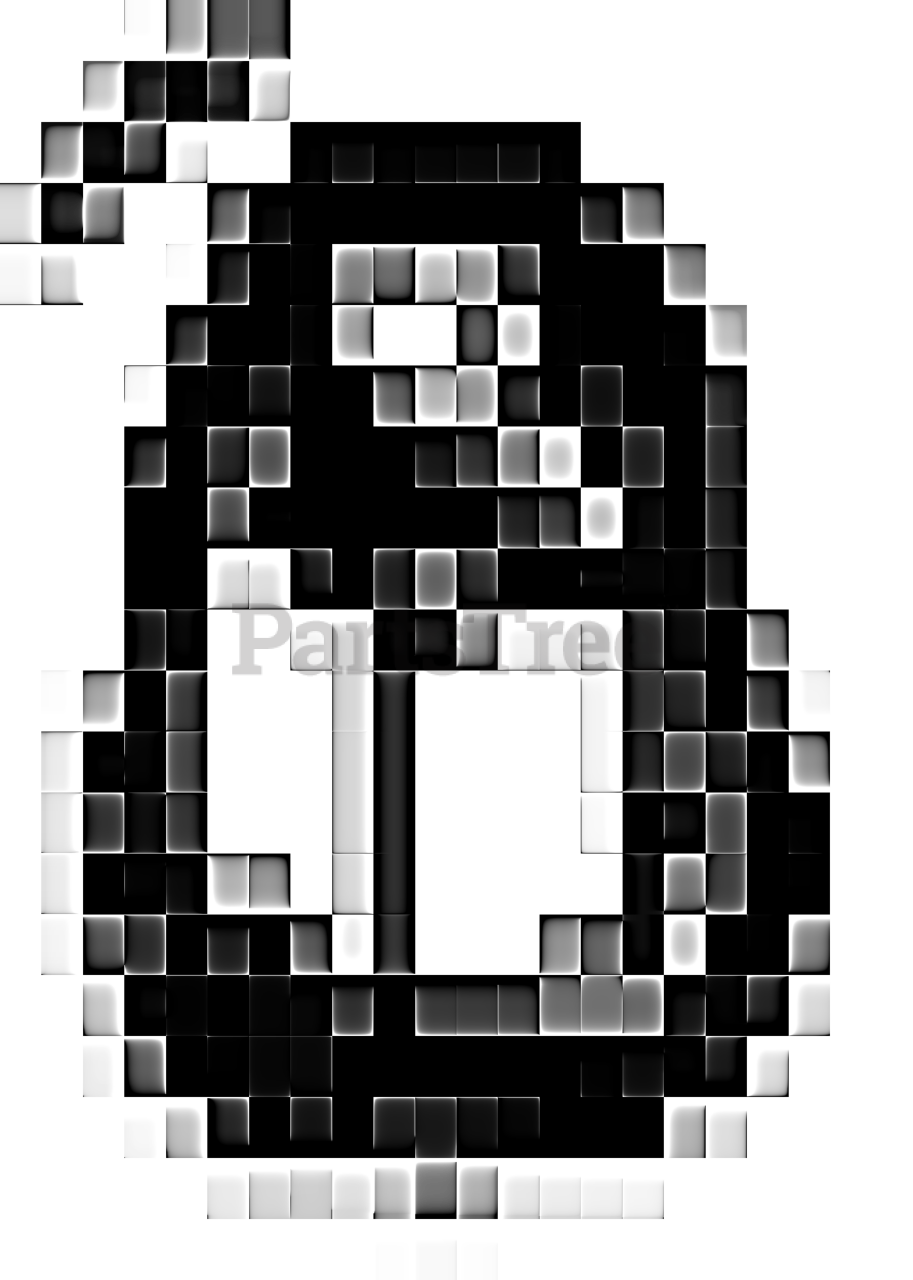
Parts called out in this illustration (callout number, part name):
9	BOLT
10	NUT FLANGE
12	LOCKNUT M8
14	WASHER
24	SCREW IHSCM
34	Hex Head Capscrew, M12 X 1.75 X 30 DIN933ZP
35	WASHER BRB 8.4X17
36	WASHER - M12
